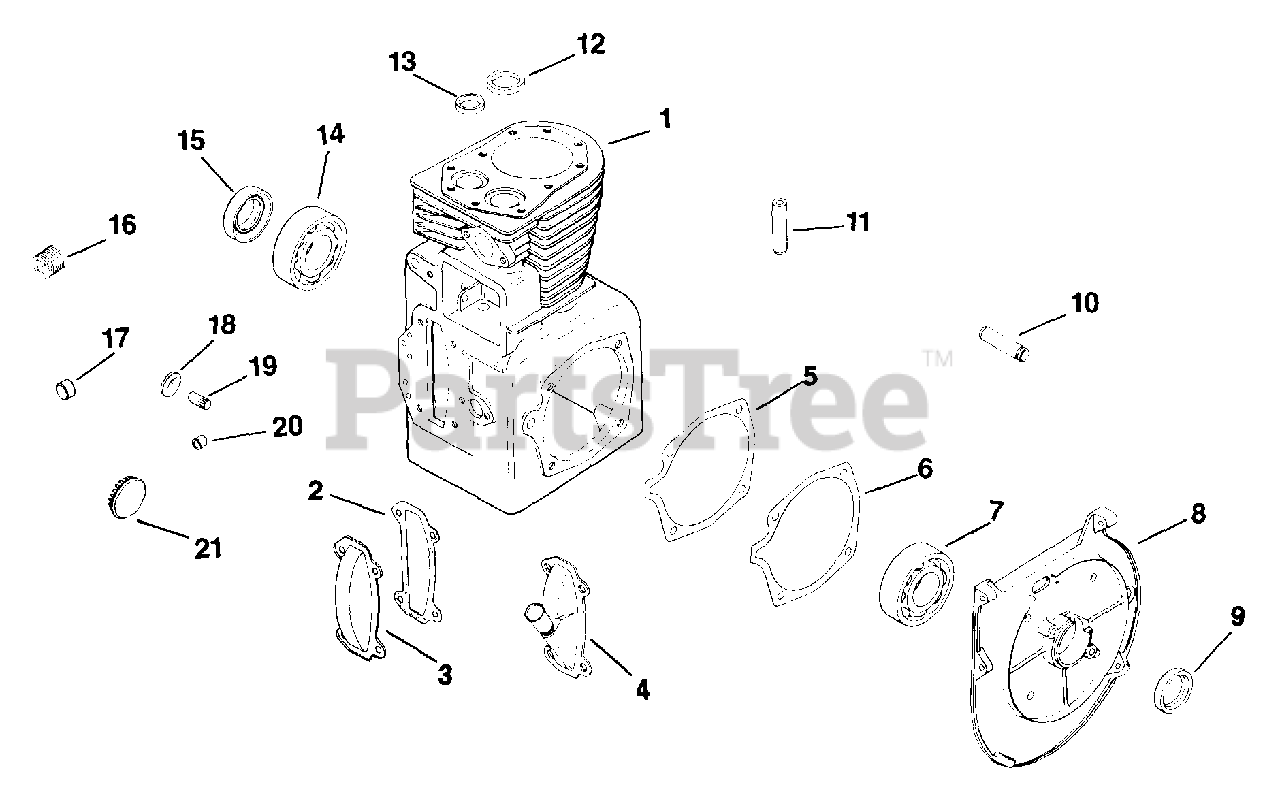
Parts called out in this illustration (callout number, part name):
1	Cylinder block
2	GASKET, CAMSHAFT COVER
3	COVER, CAMSHAFT - DISCONTINUED
5	GASKET, BEARING PLATE
6	GASKET, BEARING PLATE
7	BEARING, BALL
8	PLATE - DISCONTINUED
9	SEAL, FRONT OIL
11	GUIDE, VALVE - DISCONTINUED
12	INSERT
13	INSERT - DISCONTINUED
14	BEARING, BALL
15	SEAL, REAR OIL
16	PLUG - DISCONTINUED
18	PLUG, WELCH EXPANSION
19	SHAFT, GOVERNOR GEAR
20	BEARING
21	BUTTON PLUG - DISCONTINUED
